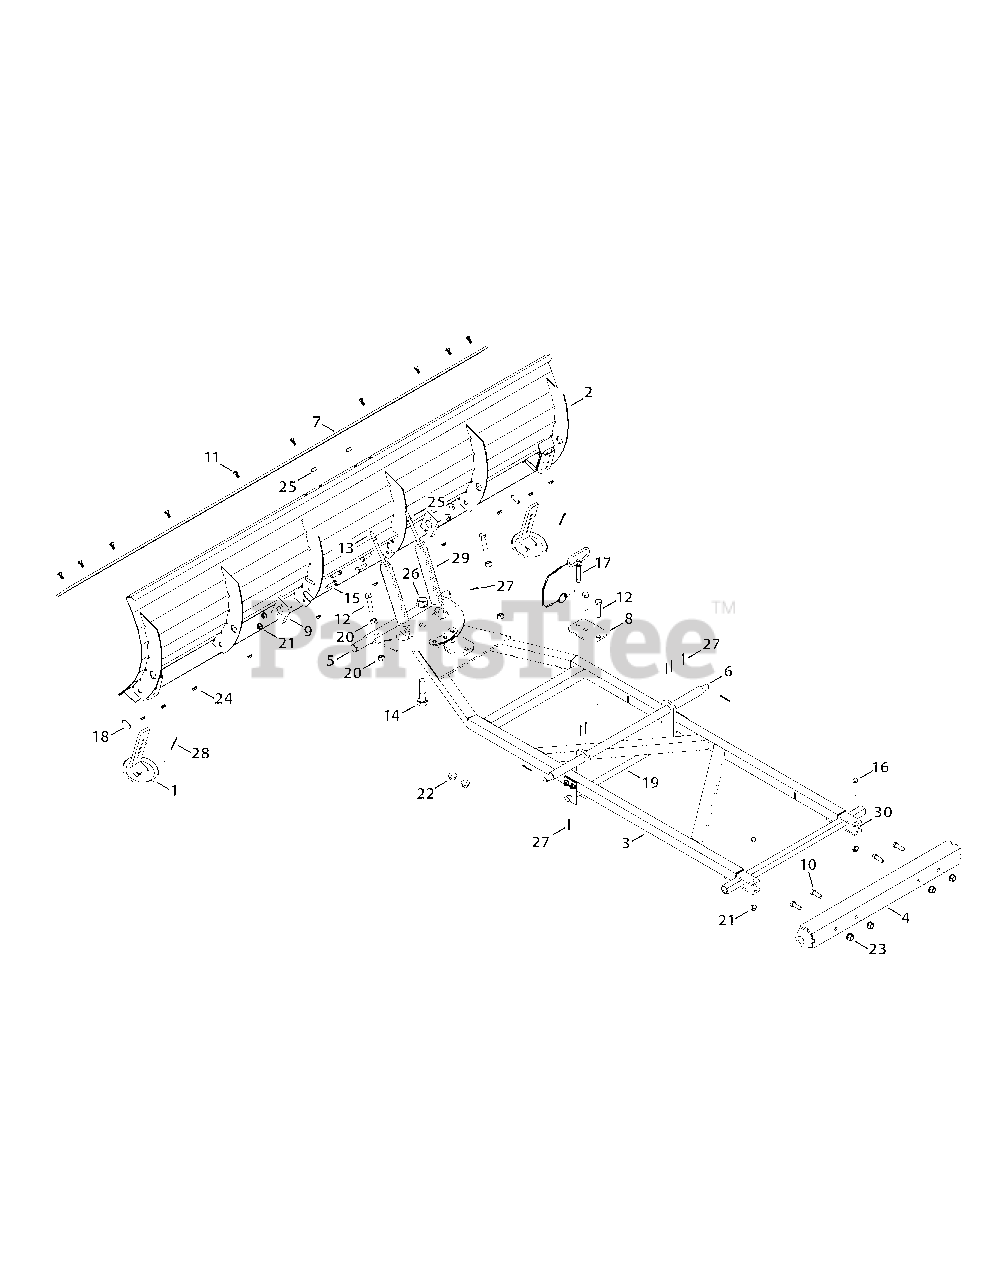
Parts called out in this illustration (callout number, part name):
2	Blade Assembly
3	Frame Assembly
4	Blade Pivot Frame
6	Lift Rod Assembly
8	Top Fixed Bracket
9	Pivot Rod Plate
10	Hex Screw, 7/16-14 x 1.25
11	Carriage Bolt, 5/16-18 x .750
12	Hex Screw, 1/2-13 x 2.00
13	Hex Screw, 3/8-16 x 4.50
14	Hex Screw, 3/4-16 x 3.00
15	Hex Screw, 3/8-16 x 1.25
16	Hex Screw, 3/8-16 x 2.00
17	Sulky Pin, .500
18	Clevis Pin, 3/8 x 1.123
19	Lift Bar
20	Hex Nut, 1/2-13
21	Flange Lock Nut, 3/8-16
22	Flange Lock Nut, 1/2-13
23	Flange Lock Nut, 7/16-14
24	Flange Counter Lock Nut, 5/16-18
25	Hex Nut, 3/8-16
26	Flange Nut, 3/4-16
27	Cotter Pin, 5/32 x 1.25
28	Cotter Pin
29	Blade Adjust Spring
30	Spacer, .385 x .635 x 1.000
